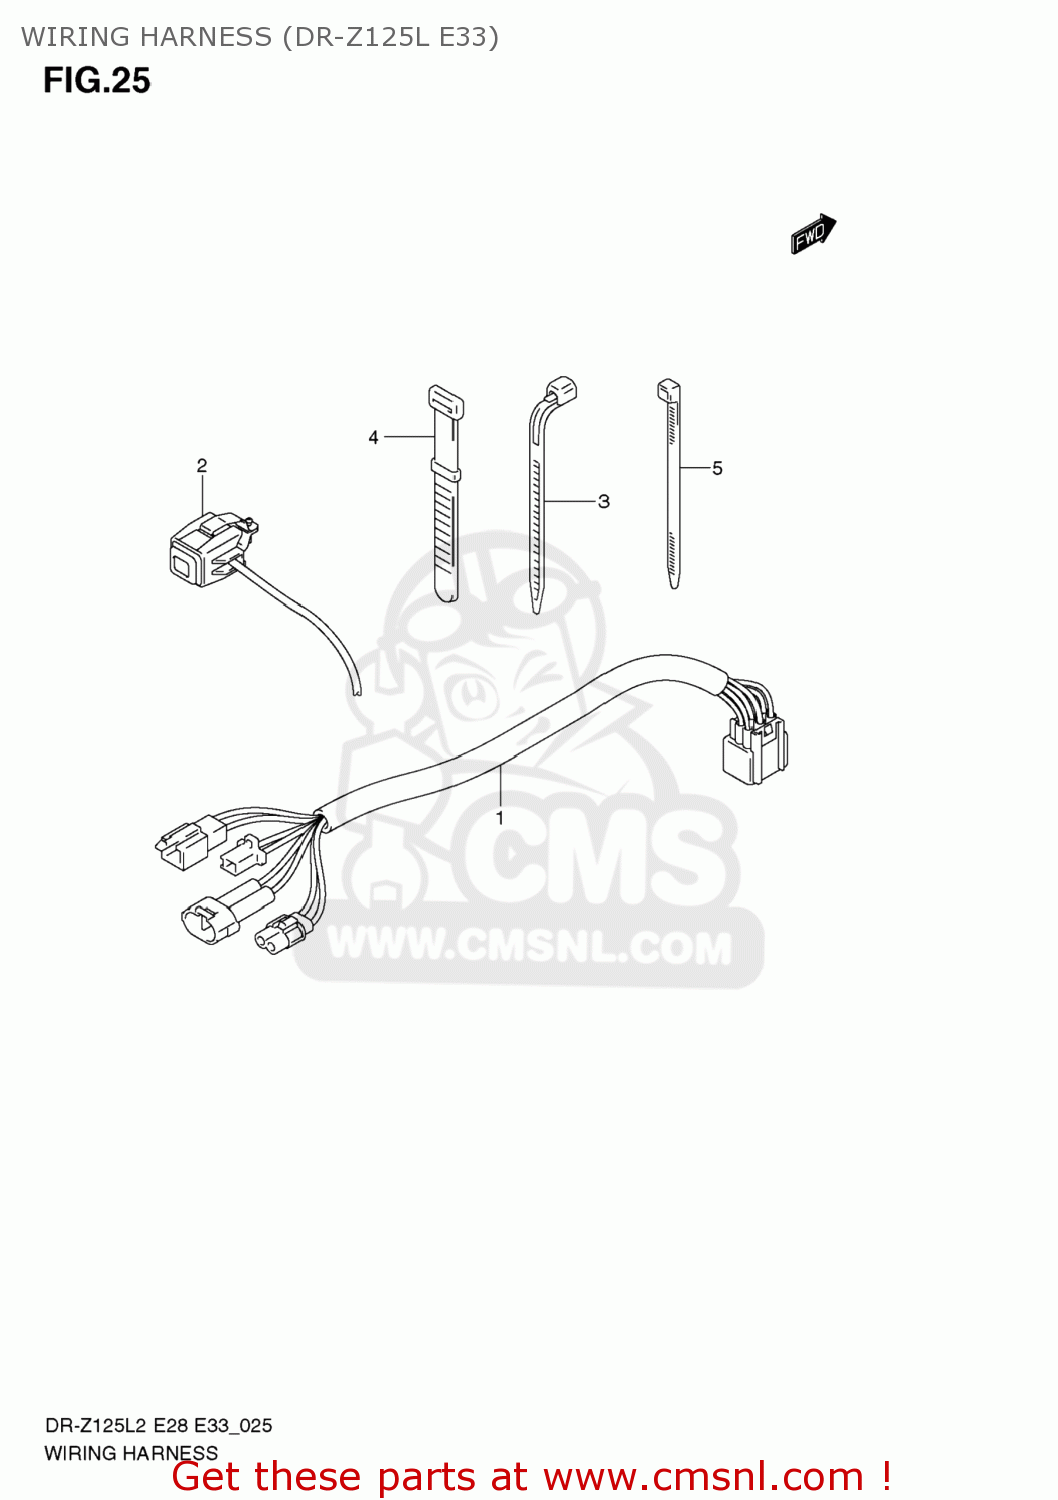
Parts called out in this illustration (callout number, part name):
1	HARNESS,WIRING
2	SWITCH ASSY,ENGINE STOP
3	CLAMP(L:165)
4	CLAMP(L:120)
5	CLAMP(L:145)
